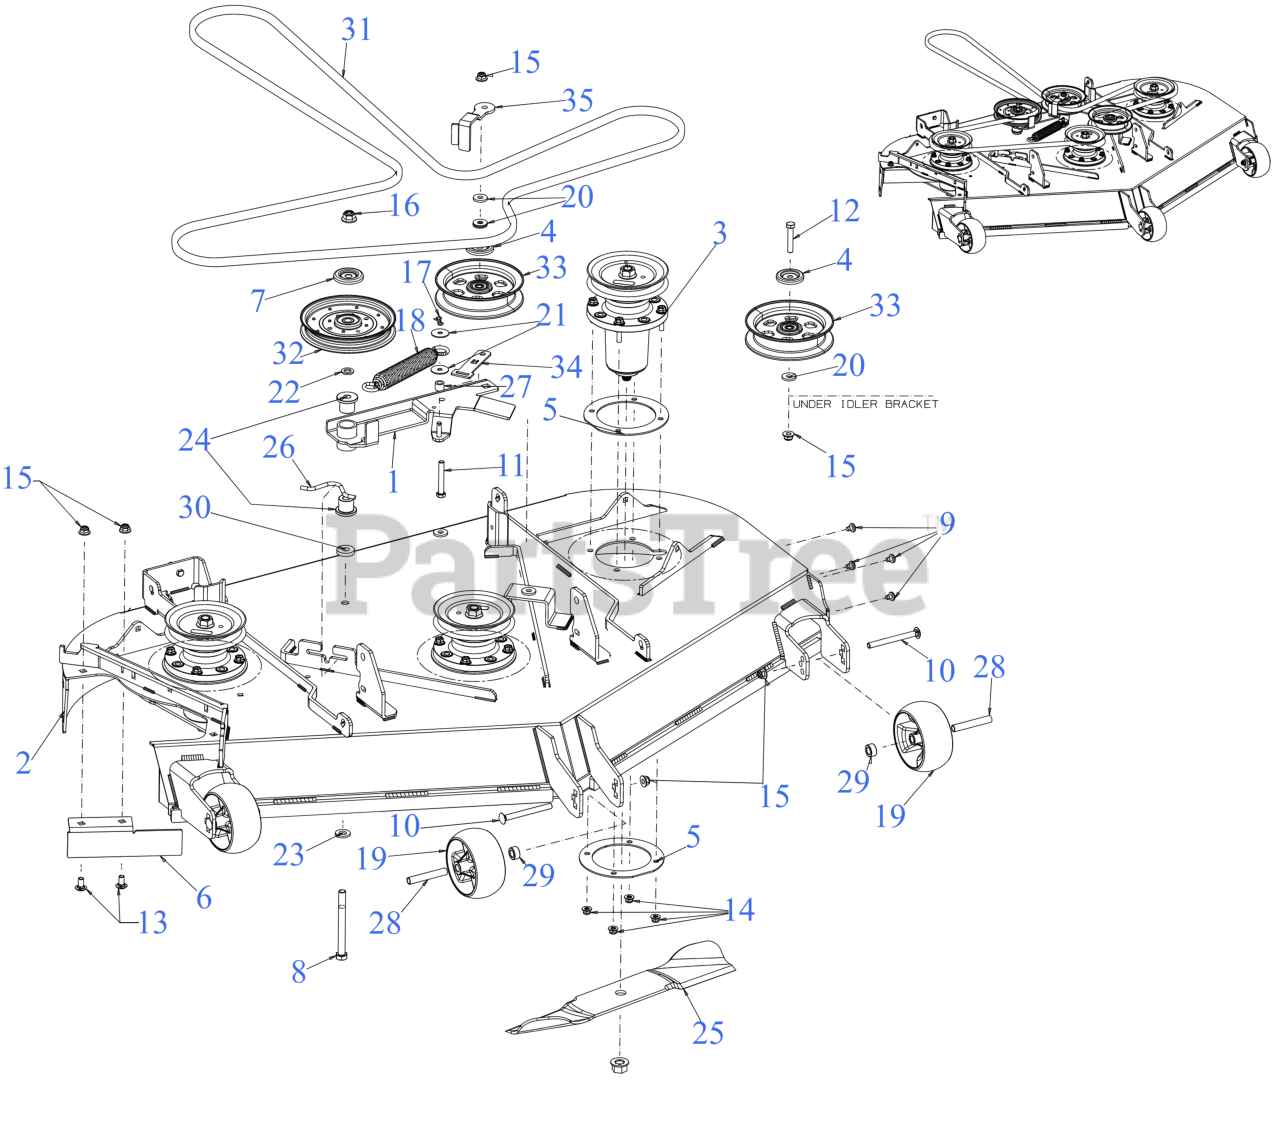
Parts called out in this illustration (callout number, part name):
1	54/60" DECK IDLER ASSEMBLY
2	54" FAB DECK SHELL
3	SPINDLE ASSEMBLY
3	Cub Cadet 54" SPINDLE ASSEMBLY (07416)
4	PULLEY CAP 1.875 DIA
5	SPINDLE PLATE
6	54" DECK CHUTE BAFFLE
7	PULLEY CAP (.540 x 2.041 DIA)
8	BOLT-HEX 1/2-13X5.0 GR5
9	SCREW 5/16-18 x .375
10	CARRIAGE BOLT 3/8-16 x 4.00 GR5
11	HEX SCREW-3/8-16X2.5 GR5
12	SCREW 3/8-16 x 2.0 GR5
13	CARRIAGE BOLT 3/8-16 x .75
14	FLANGE LOCK NUT 5/16-18
17	BOW TIE COTTER PIN 1/4-5/16
18	SPRING 1.25" DIA x 8.5" LONG
19	DECK WHEEL
19	WHEELS-DELUXE 5"
20	FLAT WASHER .385 x 1.00 x .135
21	FLAT WASHER .322 ID x 1.25 x .060
22	FLAT WASHER
23	FLAT WASHER .531X1.060X.134
24	FLANGE BEARING
25	19" BLADE
26	DECK SPRING HOOK
27	SPACER
28	SPACER .38X.49X3.05LG
29	SPACER-.505 1D
30	SPACER PLATE
31	V-BELT B SEC x 148.25
31	Cub Cadet 54" DECK DRIVE BELT
31	Troy-Bilt 54" DECK DRIVE BELT
32	IDLER PULLEY 6.0" DIA
33	5" FLAT IDLER PULLEY
34	BELT KEEPER
35	54/60" IDLER KEEPER
